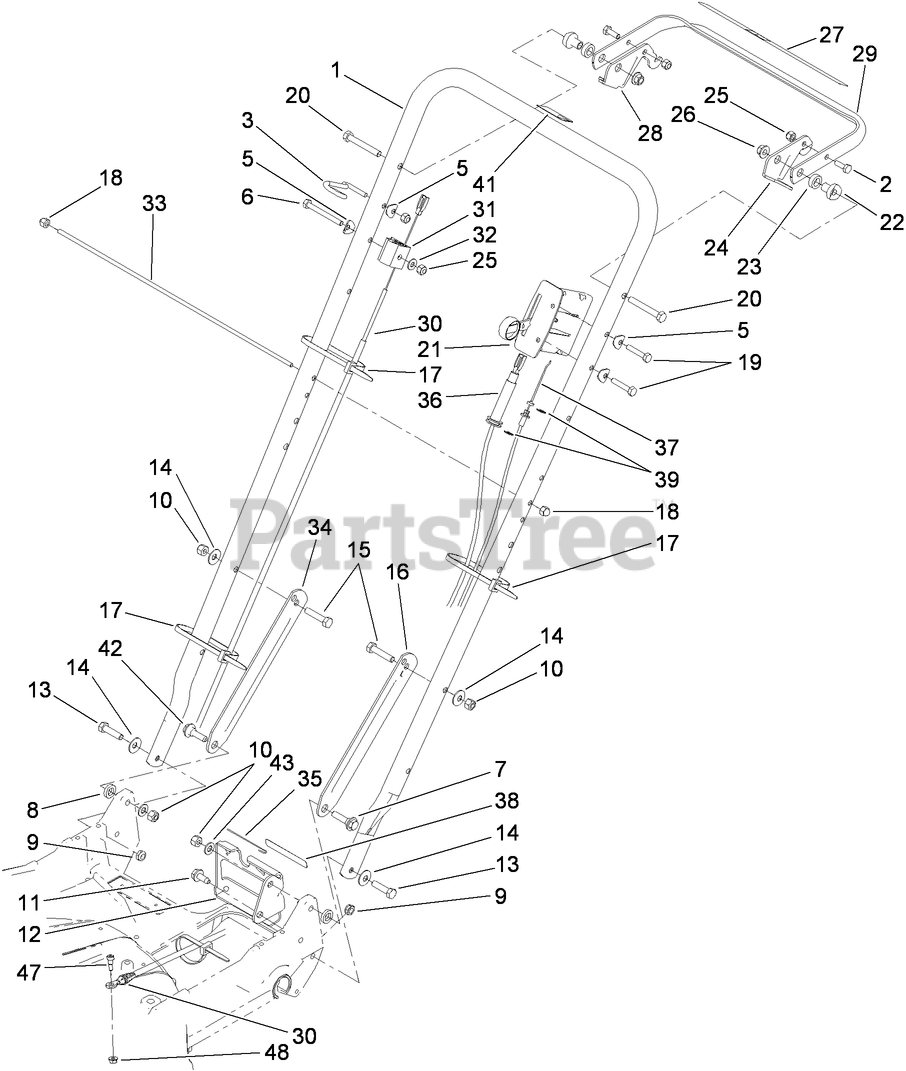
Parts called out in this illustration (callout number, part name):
2	SCREW-HH
3	GUIDE-ROPE
5	WASHER
6	SCREW-HH
7	SCREW-SHOULDER
8	SPACER
9	NUT-LOCK, NI
10	NUT-LOCK, NI
11	SCREW-HWHTF
12	BRACKET-ADJUSTMENT, TRACTION
13	SCREW-HH
14	WASHER-BELLEVILLE
15	SCREW-HH
16	LATCH-HANDLE, LH
17	TIE-CABLE
18	NUT-CAP
19	SCREW-HH
20	SCREW-HH
21	CONTROL-HEAD, THROTTLE
22	SPACER-SUPPORT
23	SPACER-NYLON
24	LEVER-CONTROL
25	NUT-LOCK, NI
26	NUT-LOCK, NI
27	DECAL-TRACTION
28	LEVER-CONTROL
29	BAR-CONTROL
30	CABLE-BRAKE, CONTROL
31	SUPPORT-CABLE
32	WASHER-FLAT
33	ROD-SUPPORT, BAG
34	LATCH-HANDLE, RH
35	RETAINER-CABLE
36	CABLE-TRACTION
37	THROTTLE CABLE ASM
38	DECAL-POSITION, GEAR
39	E-RING
41	DECAL-PROTECTION, EAR
42	SCREW-SHOULDER
43	WASHER-PLAIN
47	SCREW-SHOULDER
48	NUT-LOCK, FLANGE
